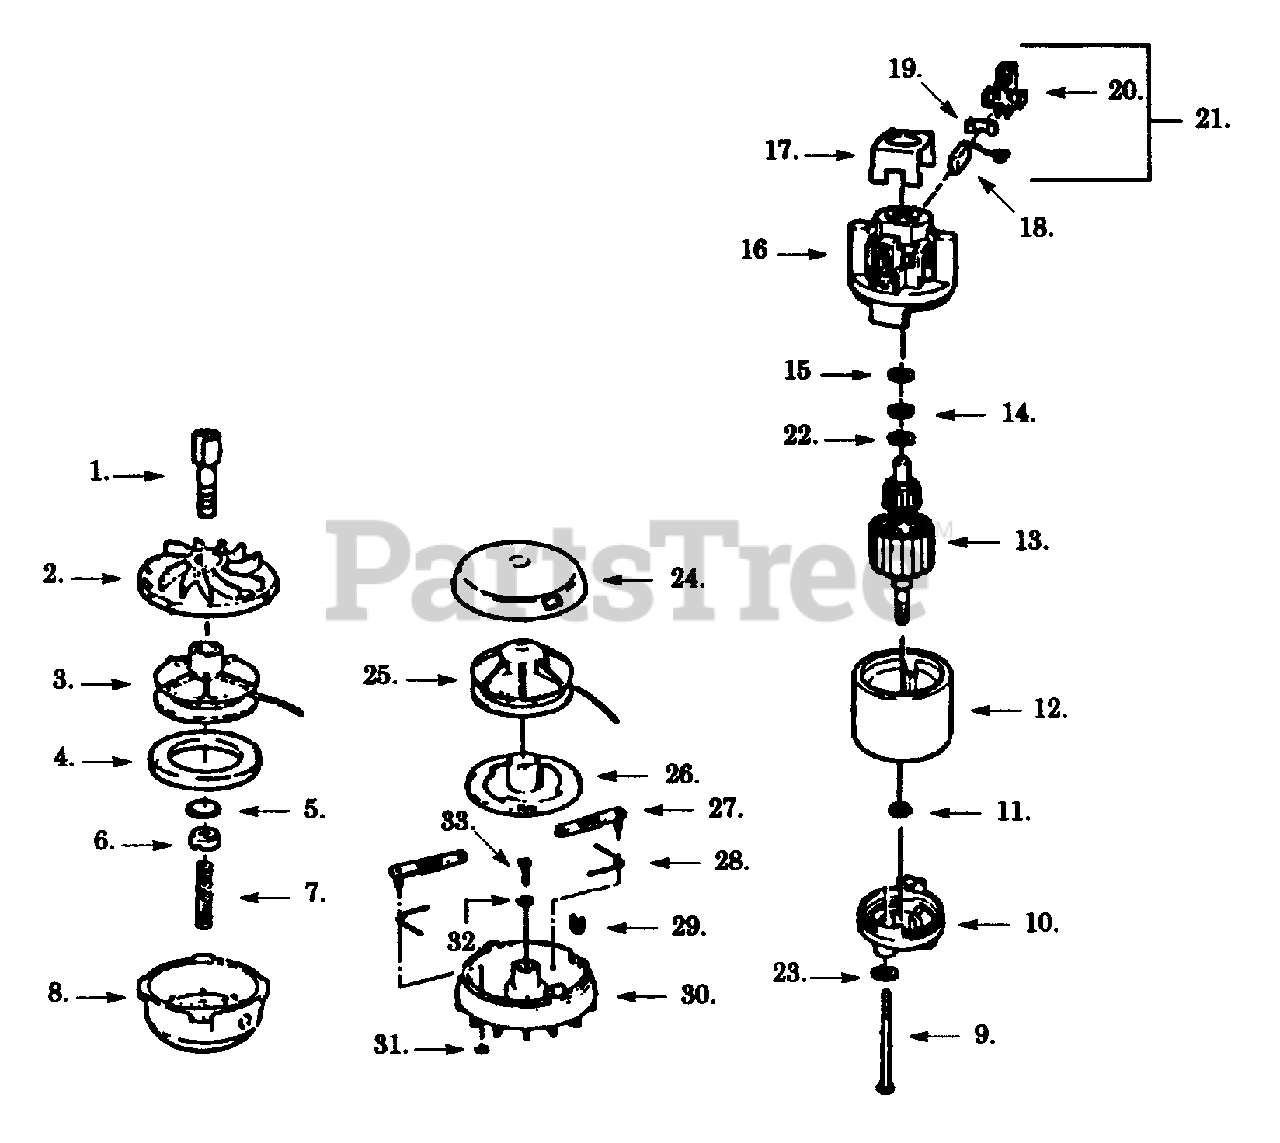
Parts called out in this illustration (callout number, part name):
1	Shaft Adapter-Model PT1000-00,PT1200-00
2	Rear Plate
4	Foam Pad
6	Adapter Nut
8	Hub Ass'y.
10	Endbell Ass'y. (Drive)
12	Field Ass'y.
13	Armature Ass'y.
14	Washer, (As required)
16	Endbell Ass'y. (Brush)
17	Insulator
19	Brush Spring
20	Brush Holder
21	Brush Kit (Incl.18-20)
25	Spool w/Line
29	Line Saver
